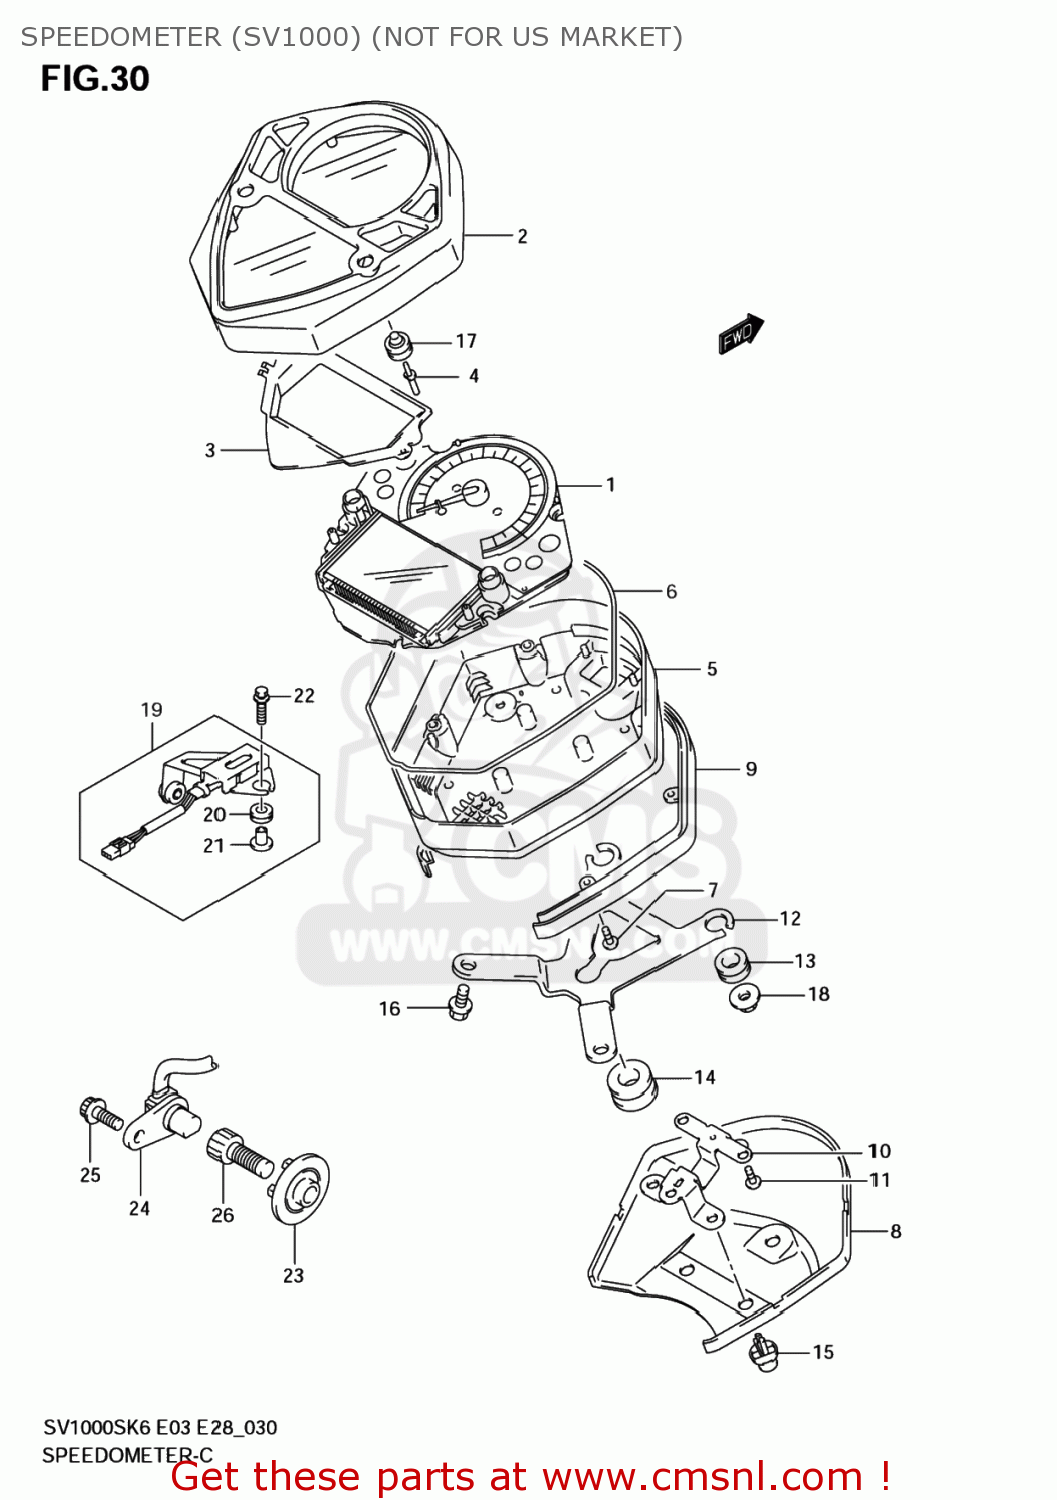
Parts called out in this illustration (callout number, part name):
1	SPEEDOMETER
2	CASE,SPEEDOMETER UPR
3	PLATE,SPEEDOMETER
4	KNOB,SPEEDOMETER
5	CASE,SPEEDOMETER LWR
6	GASKET,METER CASE (NAS)
7	SCREW,SPEEDOMETER
8	COVER,SPEEDOMETER LWR
9	DECORATION PLATE,METER CASE
10	HOLDER,SPEEDOMETER
11	SCREW(4X14)
12	BRACKET,SPEEDOMETER
13	CUSHION,METER
14	CUSHION
15	CLIP
16	BOLT MAGNETO S
17	COVER,SPEEDOMETER KNOB
18	NUT
19	RESISTOR ASSY
20	CUSHION
21	SPACER(6.5X10X11.6)
22	BOLT(6X25)
23	ROTOR,SPEED
24	SENSOR,SPEED
25	BOLT
26	BOLT
